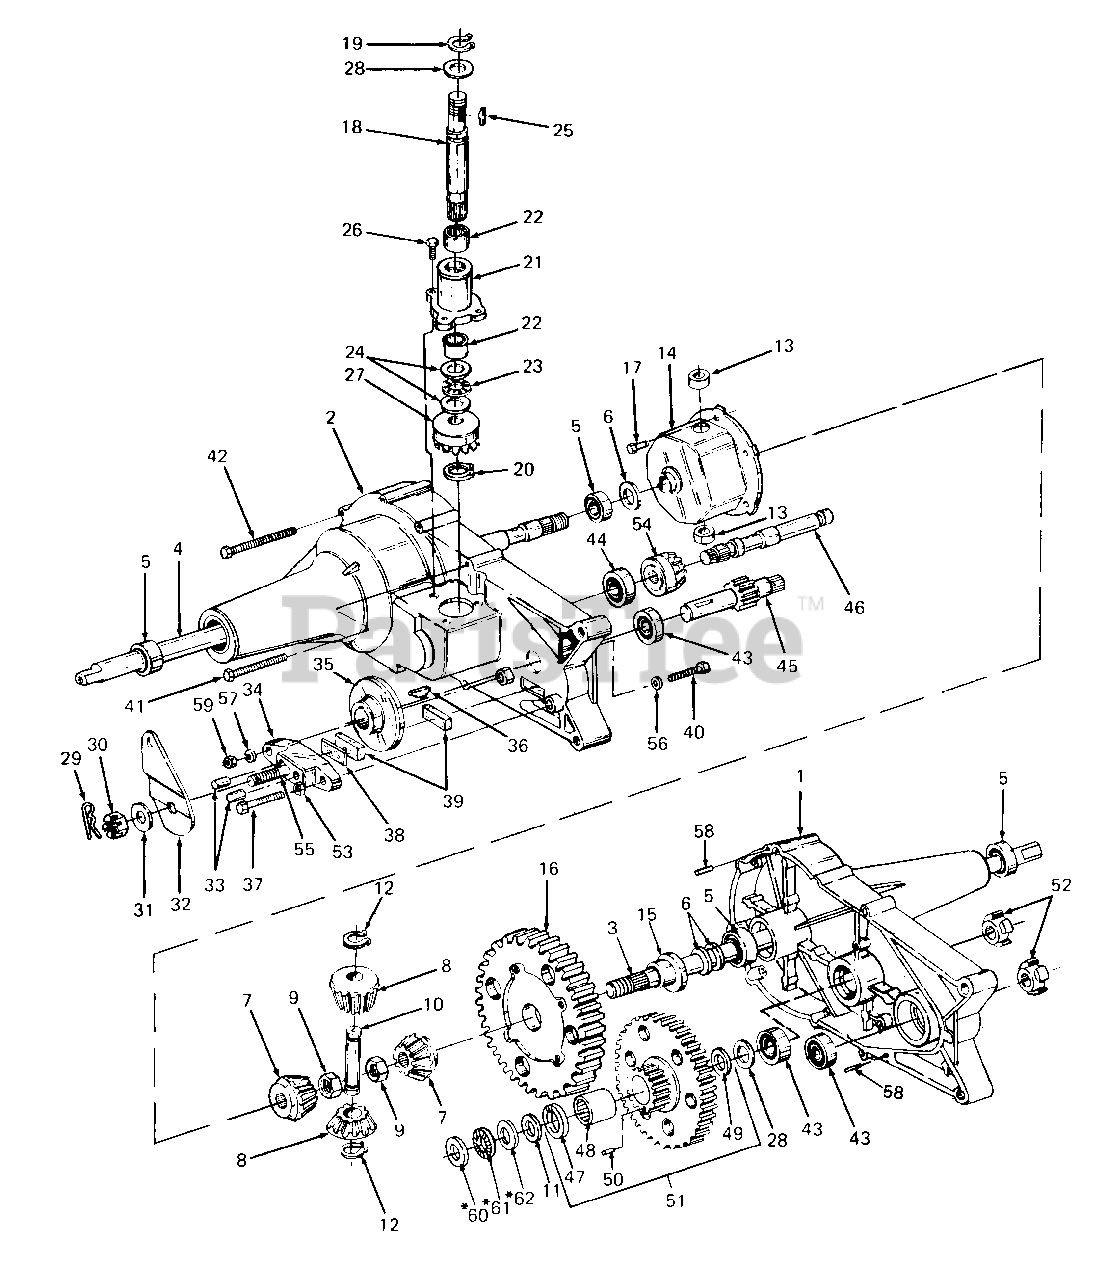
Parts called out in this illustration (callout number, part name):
1	Housing Half, LH
2	Housing Half, RH
5	Bearing, Ball
6	Washer, Flat, .76 X 1.5 X .306 Thk HDN
7	Gear, Miter
8	Gear, Miter
9	Nut, Hex Jam Patch Lock, 1/2-20
10	Shaft, Cross
11	Washer, Flat, .62 ID X 1.0 OD X .050 Thk
12	Ring, Snap
13	Bearing, Thrust
14	Housing Assy, Differential
15	Bearing, Flange, .75 ID X .587
16	Gear, Differential, 72 Tooth
17	Bolt, Hex Wash Hd Patch, 1/4-28 X .62 Lg
18	Shaft, Input
19	Ring, Snap
20	Ring, Retaining, Ext, 7/16 Dia
21	Bearing, Input Housing
22	Bearing, Needle, 5/8 ID X .50 Lg
23	Bearing, Thrust
24	Washer, Flat, 5/8 ID X 1.12 OD X .030 Thk
25	Key, #4 Hi-Pro, 3/32 X 5/8 Dia Hdn
26	Screw, Hex Patch Lock, 1/4-20 X 3/4 Lg
27	Gear, Input Pinion, 17 Tooth
28	Washer, Flat, .62 ID X 1.0 OD X .050 Thk
29	Pin, Cotter
30	Nut, Castle, 5/16-24
31	Washer, Flat, .343 X .88 X .062 Thk
32	Arm, Brake Actuator
33	Pin, Actuating, 5/16 Dia
34	Yoke, Brake
35	Disc, Brake
36	Key, Hi-Pro, 3/16 X 5/8 Dia
37	Screw, Hex Patch Lock, 1/4-20 X 1.5 Lg
38	Plate, Puck
39	Puck, Brake
40	Screw, Hex Cap, 1/4-20 X 1.5 Lg
41	Screw, Hex Self-Tapp, 1/4-20 X 2.0 Lg
42	Screw, Hex Self-Tapp, 1/4-20 X 2.75 Lg
43	Bearing, Ball
44	Bearing, Ball
45	Shaft, Pinion w/11 Tooth Gear
46	Shaft, Drive
47	Bearing, Bronze Thrust
48	Bearing, Needle
49	Seal, Grease
50	Pin, Dowel, 3/32 Dia X .25 Lg
51	Gear Assy, 60 & 17 Tooth
52	Coupling
53	Nut, Hex Jam, 1/4-20
54	Gear, Drive Pinion, 17 Tooth
55	Bolt, Square Hd, 5/16-24
56	Washer, Flat, .265 X .938 X .12 Thk
57	Washer, Lock, 1/4
58	Pin, Roll, 3/16 Dia X .50 Lg
59	Nut, Hex, 1/4-20
60	Washer, Flat, .62 ID X 1.12 OD X .060 Thk
61	Bearing Thrust
62	Washer, Flat, .62 ID X 1.12 OD X .030 Thk
